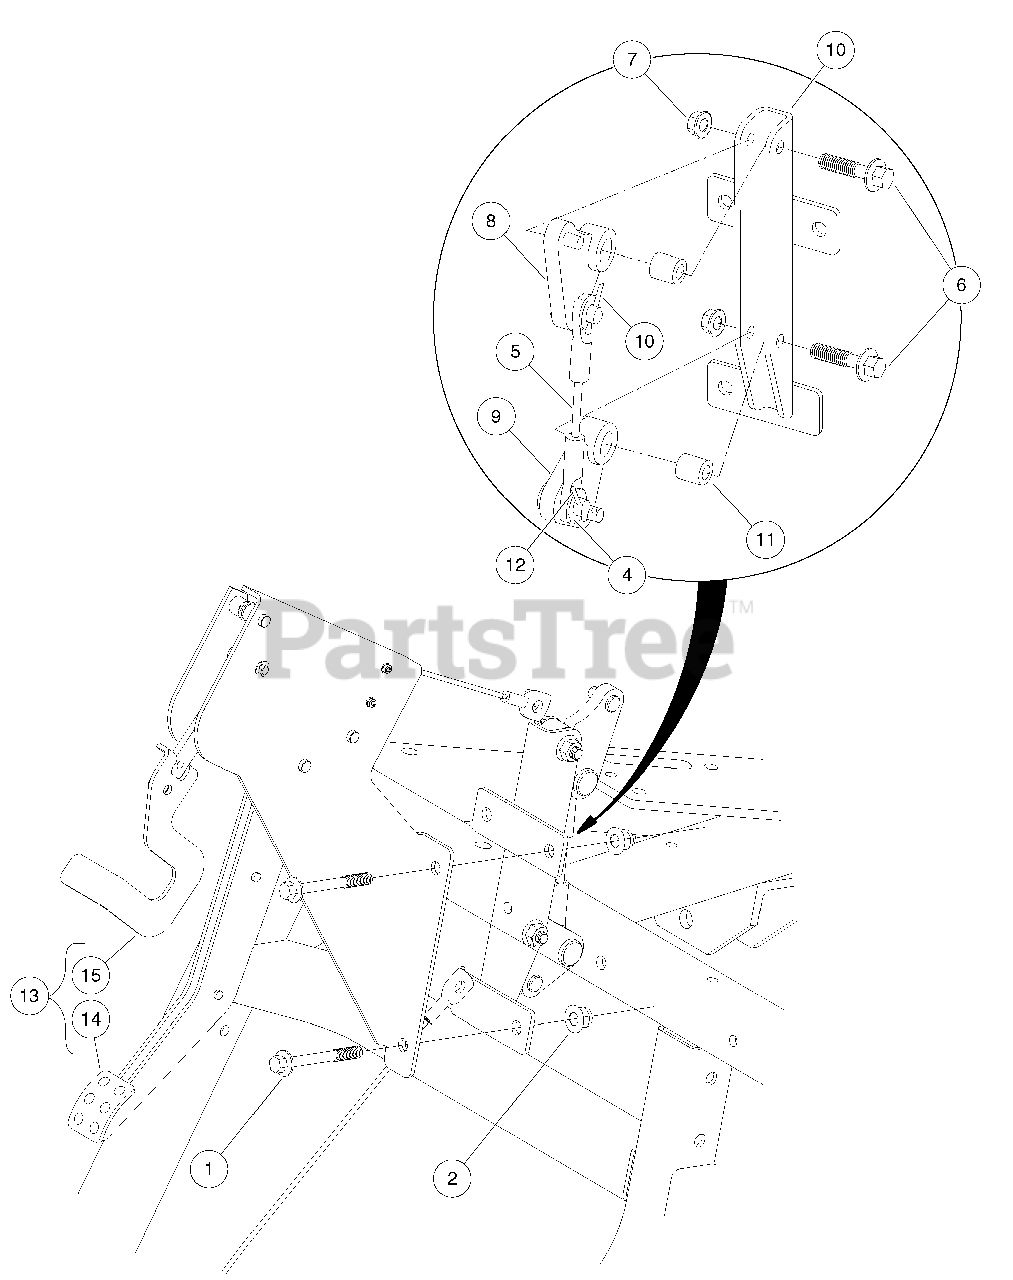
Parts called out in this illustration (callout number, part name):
1	Bolt Flanged Head, M8 X 1.25 X 65
2	Lock Nut, Flg M8 X 1.25 Nylon
3	Asm, Sub, Bracket, Park Brake
4	Washer, Flat, 3/8, Blk Fin
5	Cable, Crank, Bell
6	Bolt Flg, M8x1.25 X 35, Gr10.9
7	Nut Flg M8 X 1.25 Gr 10
8	Asm, Bellcrank, Upper
9	Asm, Bellcrank, Lower
10	Brkt, Bellcrank, Prk Brk, Awd
11	Spacer, Pivot, Park Brk, Awd
12	Cotter Pin, 3/32 x 1
13	Asm, Pedal, Brake, Hard
14	Pedal, Brake, Park
15	Handle, Release, Park Brake
